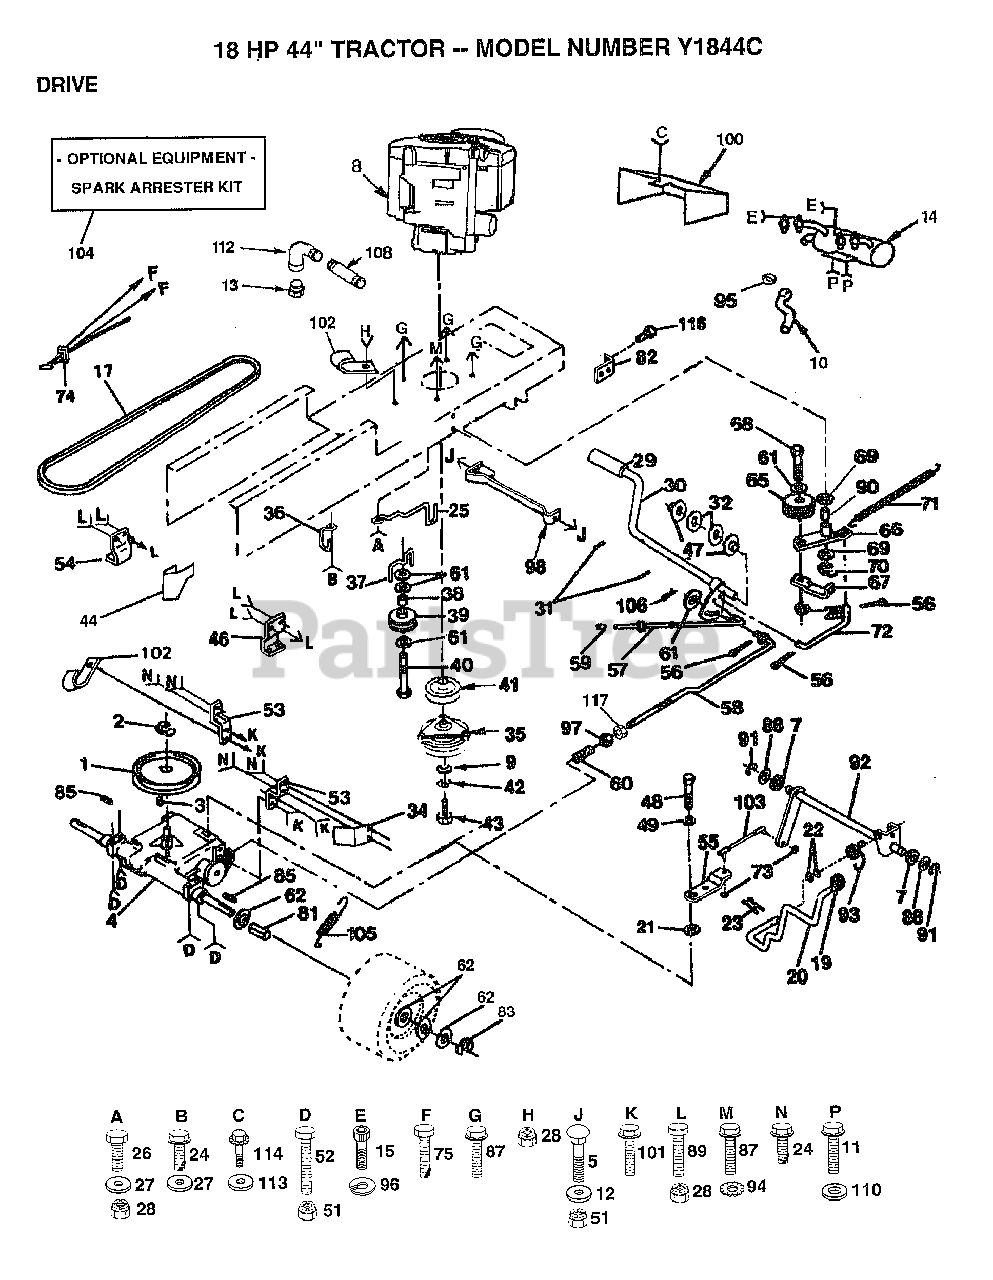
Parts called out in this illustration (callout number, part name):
1	PULLEY TRANSAXLE
2	RING
4	TRANSAX. PRLES.
5	BOLT
7	BUSHING
9	WASHER
12	WASHER T
15	SCREW
17	BELT.GRDRV.94.75
19	KNOB.DUCKHEAD.1/2
21	WASH-SHFT PLT LT
22	WASHER
23	PIN COTTER 1/8
24	SCREW
25	KEEPER.BELT.ENG.L
26	BOLT
27	WASHER
29	PEDAL COVER T
32	WASHER LT
34	"KEEPER,BELT RH"
37	BELT KEEPER LT
38	SPACER T
39	PULLEY.IDLER.FLAT
40	BOLT
41	PULLEY ENGINE
42	LOCKWASHER
44	KEEPER BELT LH
46	BRKT TRANS RH
47	NYLON BEARING
49	WASHER PM
52	BOLT
53	STRAP TORQUE
54	BRKT TRANS LH
55	"ARM,SHIFT"
56	COTTER PIN
57	BRAKE PARK ROD
58	ROD BRAKE
59	PLUNGER CAP T
60	"SPRING,ROD BRAKE"
61	WASHER
62	WASHER
66	ARM IDLER
67	RETAIN BELT
69	WASHER LT
70	KLIP RING
71	"SPRING, RETURN LT"
72	"LINK, CLUTCH T"
73	NUT 1/4-28
74	CONTROL.THROTTL
75	SCREW LT
81	SPACER HYT
82	BRACKET LT
83	E RING HYT
85	SQ KEY STD
87	SCREW LT
88	WASHER D
90	"LY, BEARING"
91	KLIP RING
92	"SHAFT,SHIFTER"
93	"SPRING,TORSION"
94	LOCKWASHER
95	MUFFLER CLAMP
96	LOCKWASHER
97	NUT
98	BRACKET.ASM.MTG
101	SCREW
102	CLIP T
103	"ROD,TIE "
104	SPARK ARREST KIT
106	RETAINER M
108	PIPE NIPPLE LT
110	LOCKWASHER
112	ELBOW
116	SCREW
117	NUT
